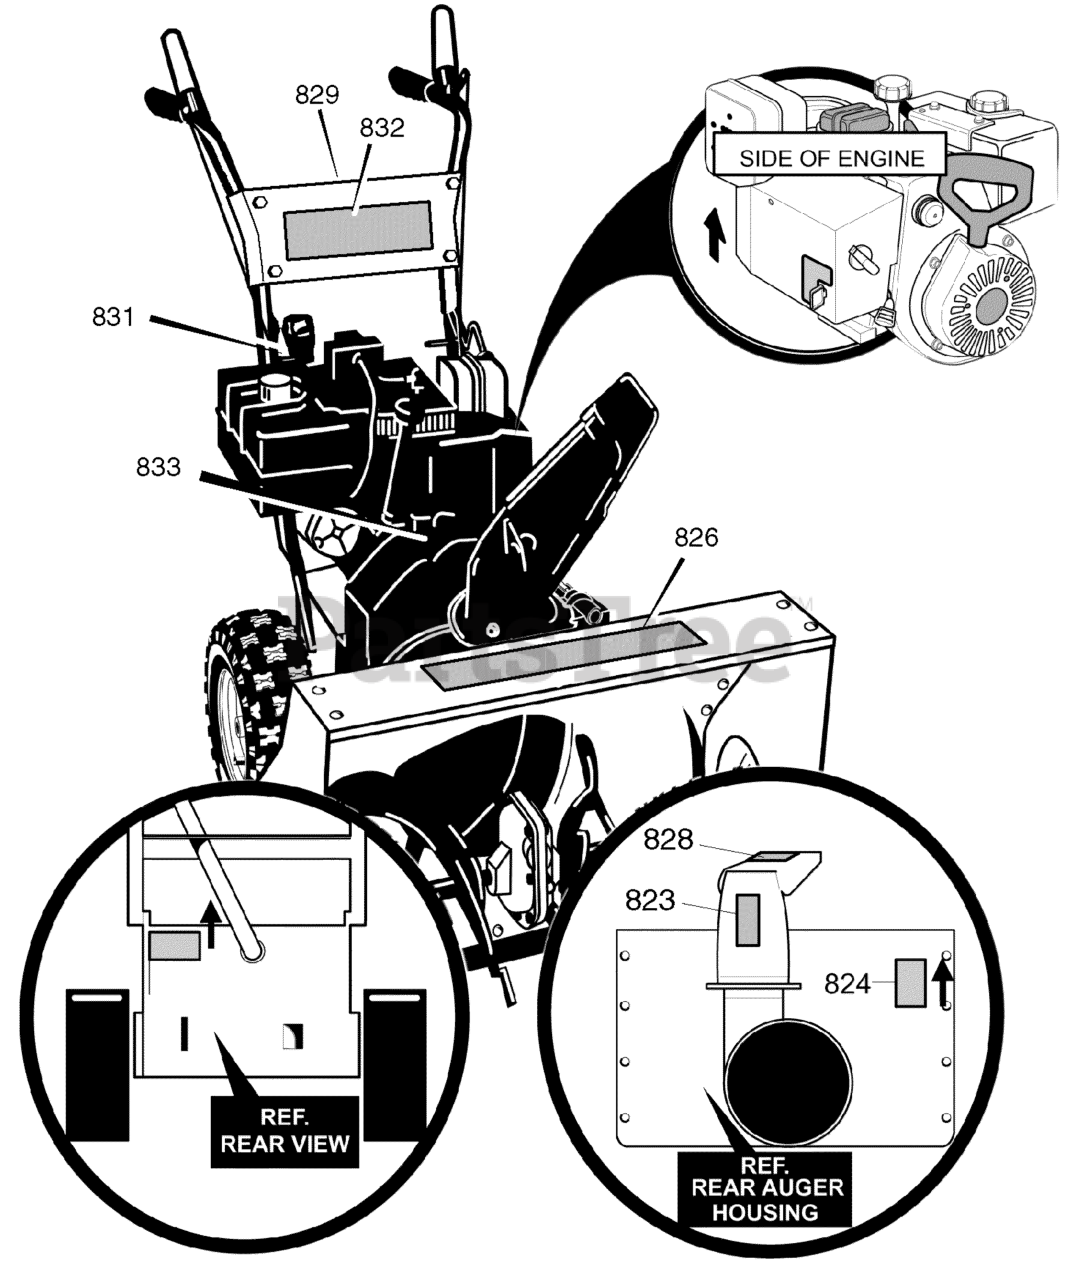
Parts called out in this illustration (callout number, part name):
823	DECAL, DANGER CHUTE HAND
824	DECAL, DANGER FOOT
826	DECAL, CRAFTSMAN 10.5/29
828	DECAL, THROWN OBJECTS
829	DECAL, DRIVE CLUTCH / AUGER
831	DECAL, GEAR SELECTOR
832	DECAL, CRAFTSMAN
833	DECAL, LID, TOOL BOX
